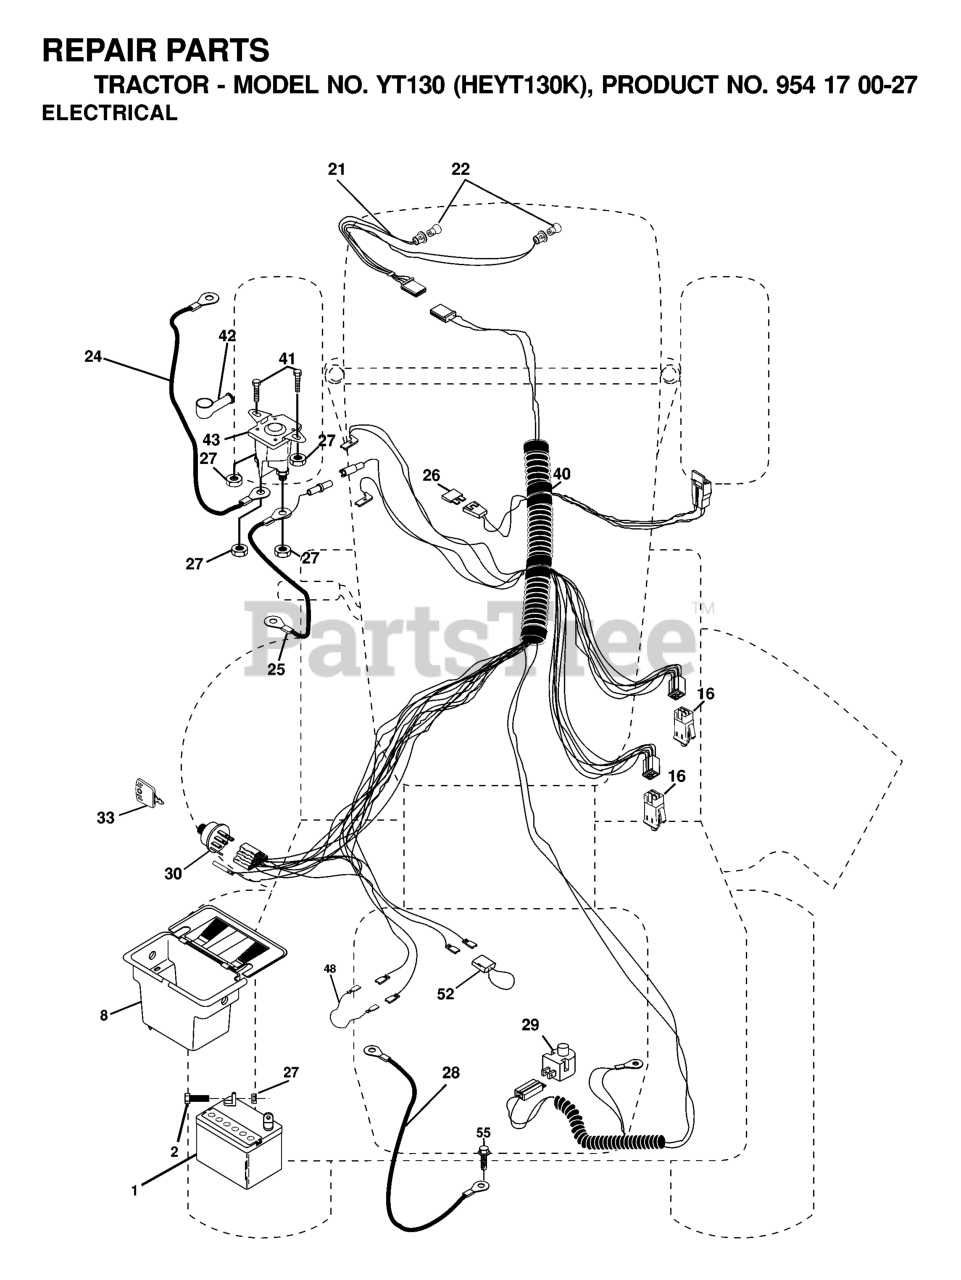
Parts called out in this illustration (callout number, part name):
1	V-BELT 3L SECTION
2	BOLT HEX .44-14 X 1.25 GRADE 5
3	IDLER FLAT 1.75 X .47
4	NUT-LOCKING-CENTER .31-18
5	WASHER FLAT STL .323X.625X.062
6	SPACER .52 X .45 X .34
8	BSHNG FLG .325X.501X.250X1.120
9	BOLT-HEX .31-18 X .75 GRADE 5
10	NUT LOCKING CENTER .44-14
11	SPRING TENSION .043X.44X3.31
13	WASHER-LOCK .38X.094
14	BOLT HEX .38-24 X 2.00
15	WASHER FLT STL .390X1.50X.125
